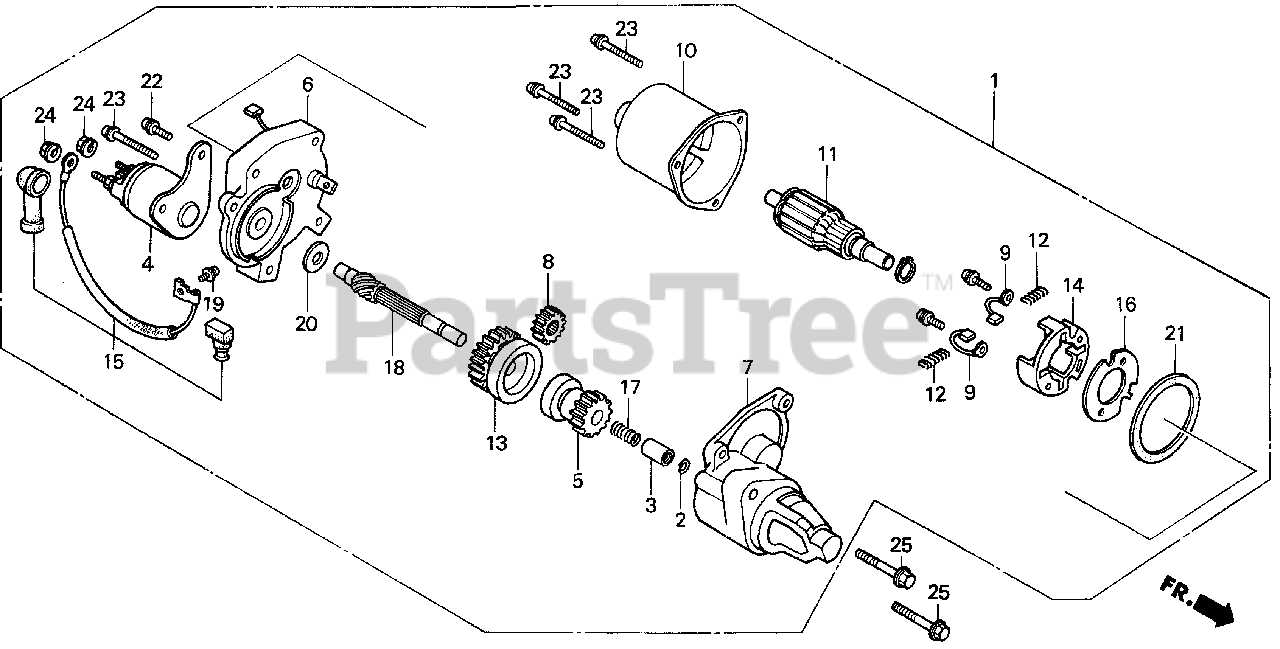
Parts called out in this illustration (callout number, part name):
1	MOTOR ASSY., STARTER
2	RING, SNAP
3	COLLAR, CLUTCH
4	CONTACTOR ASSY.
5	CLUTCH, OVERRUNNING
6	BRACKET, CENTER
7	BRACKET, FR.
8	GEAR, DRIVE PINION
9	BRUSH
10	YOKE
11	ARMATURE
12	SPRING, BRUSH RETURN
13	GEAR, REDUCTION
14	HOLDER, BRUSH
15	WIRE, WATER COVER
16	INSULATOR
17	SPRING
18	SHAFT
19	SCREW-WASHER (4X6)
20	WASHER
21	GASKET
22	BOLT-WASHER (5X14)
22	SCREW-WASHER (5X14)
23	SCREW-WASHER (5X3)
24	NUT-WASHER (6MM)
25	BOLT, FLANGE (8X40)
